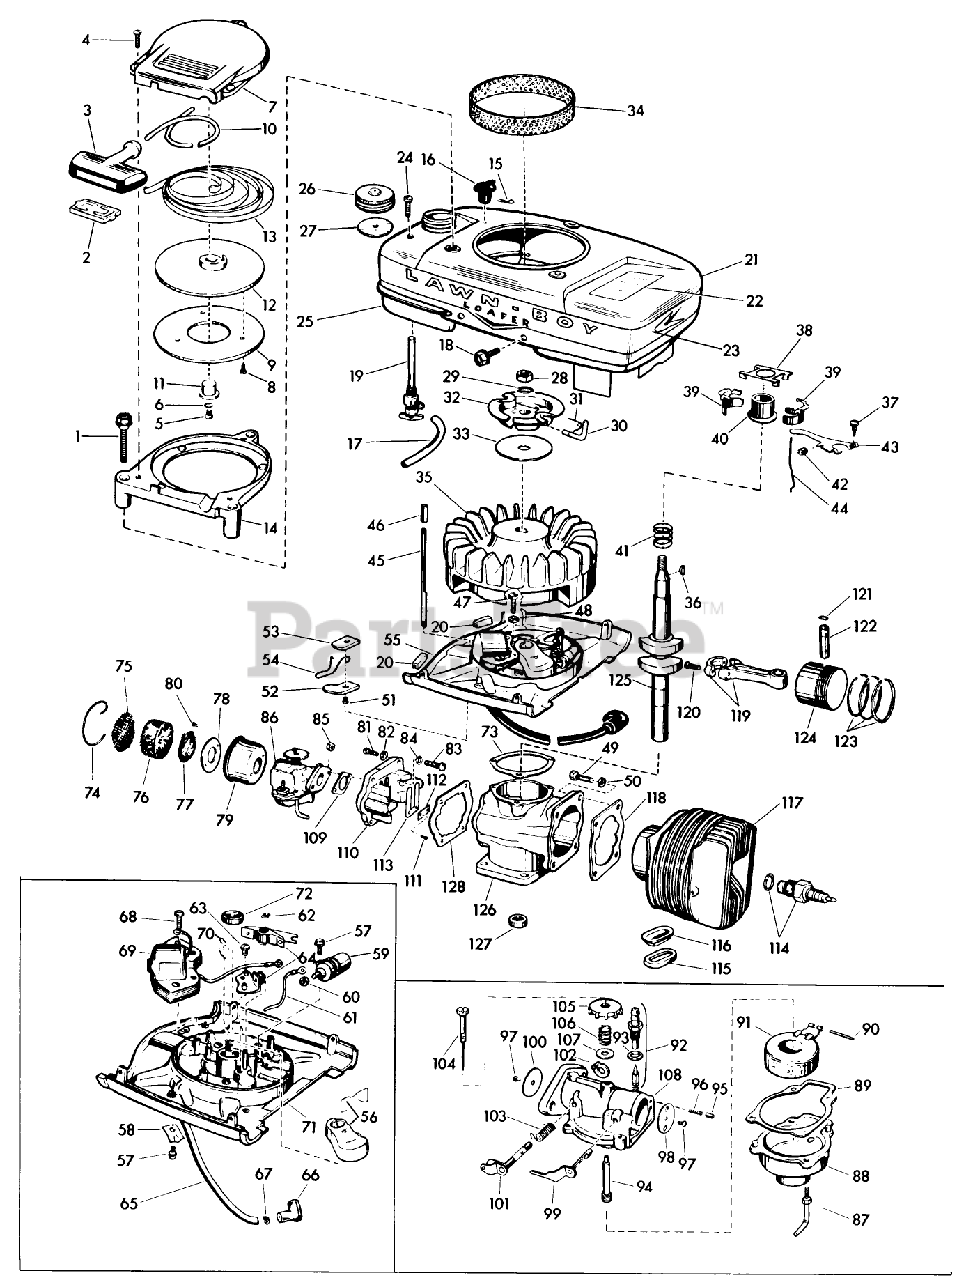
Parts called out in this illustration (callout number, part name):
9	Plate-Pulley
13	RECOIL SPRING
14	Base-Starter
15	Cotter Pin-Choke Knob
16	KNOB, CHOKE BAR
18	SCREW S
19	VALVE&SCREEN SM
23	Decal-"Lawn-Boy"
26	Gas Cap
30	PIN - STARTER
34	Screen-Flywheel
40	COLLAR S
42	WEAR BLOCK S
43	GOVERNER LEVER AY
44	GOVERNOR ROD S
51	Screw Shut-off Switch
64	BREAKER AY. S
66	Cover-Rubber
73	GASKET S
74	Clip-Air Filter
76	ELEMENT
78	BACK-UP PLATE
81	SCREW S
85	STOP NUT
97	Screw-Choke Disc
99	CHOKE SHAFT&LVR AY
103	SPRING
104	NEEDLE AY. S
106	Spring-Ndl. Adj.
109	GASKET S
112	PLATE-BACKUP, REED
114	Spark Plug
120	Screw-Connecting Rod
125	Crankshaft
128	GASKET
